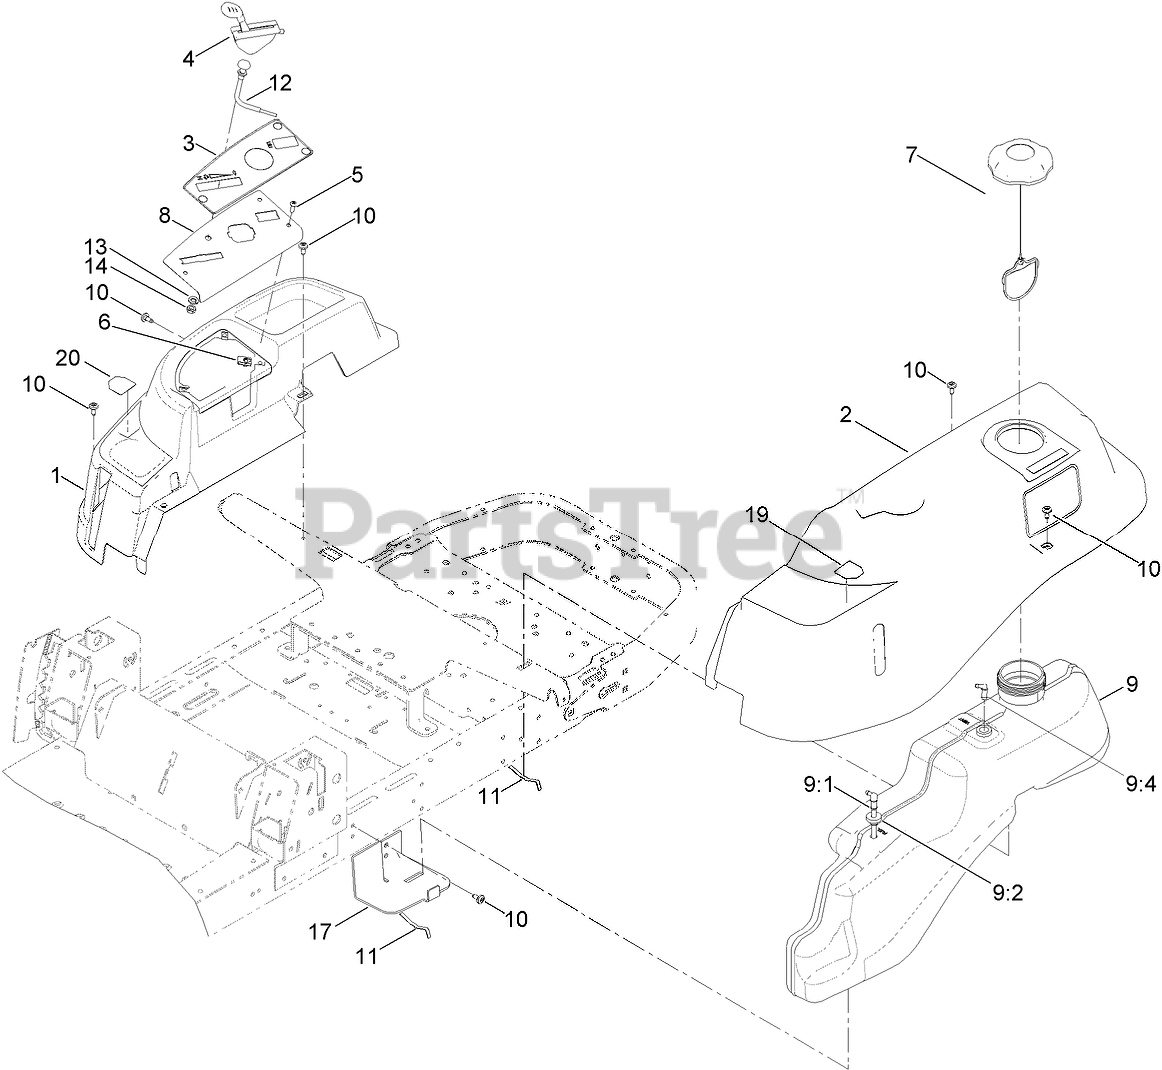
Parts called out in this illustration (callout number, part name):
1	POD-RH
2	POD-LH
3	DECAL-PANEL, CONTROL
4	CABLE-THROTTLE
5	SCREW-PRH
7	CAP-FUEL, RATCHETING
8	PLATE-CONTROL
9	FUEL TANK ASM
9:1	CONNECTOR-ELBOW, 90 DEG
9:2	BUSHING
9:4	FITTING-PLASTIC
10	SCREW-SHOULDER
11	SPRING
12	CABLE-CHOKE
13	WASHER-LOCK
14	NUT-HJ
17	SUPPORT-TANK, FRONT
19	DECAL-CONTROL LEVER, LH
20	DECAL-CONTROL LEVER, RH
